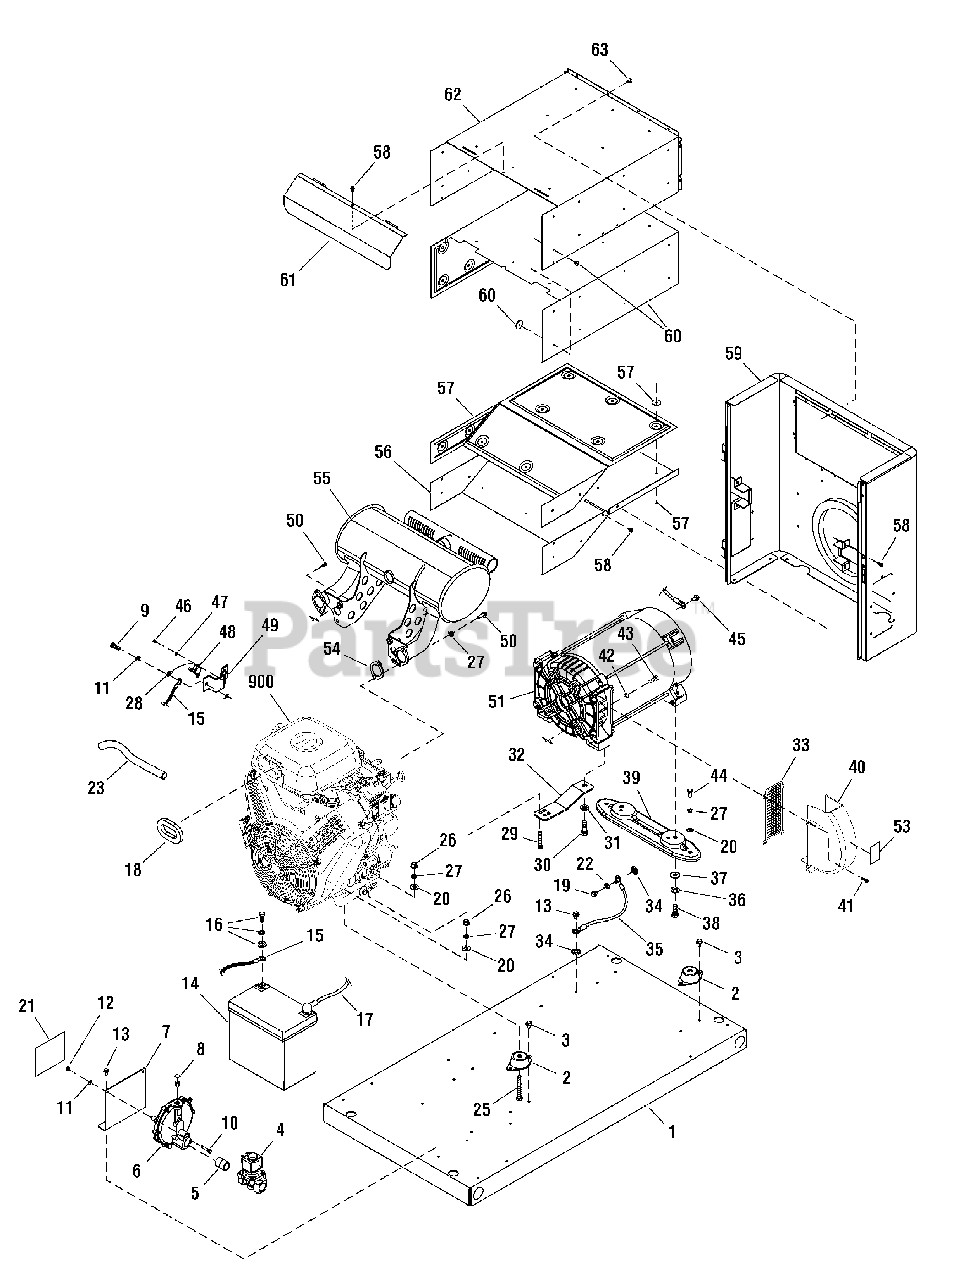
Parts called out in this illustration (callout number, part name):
1	BASE
2	MOUNT, Vibration
4	SOLENOID, Gas Fuel
6	REGULATOR, NG/LPG
7	BRACKET
9	* CAPSCREW, Hex Head, M6-1.0 x 16
10	* CAPSCREW, Hex Head, M6-1.0 x 30
11	* WASHER, Lock, 1/4
12	* NUT, M6-1.0
13	BOLT
16	KIT, Hardware, Battery
18	TUBE
20	* WASHER, Flat, 5/16-M8
22	* WASHER, Shakeproof, M6
23	HOSE, Oil Drain
25	* CAPSCREW, Hex Head, 5/16-18 x 2-1/2
26	* NUT, 5/16-18
27	* WASHER, Lock, 5/16-M8
29	* CAPSCREW, Hex Head, 5/16-18 x 2
30	* CAPSCREW, Hex Head, M12-1.75 x 35
31	* WASHER, M12
32	SUPPORT, Engine
34	* WASHER, Shakeproof, M6-1/4
36	* WASHER, Lock, 3/8
37	* WASHER, Flat, 3/8
38	* CAPSCREW, Hex Head, 3/8-16 x 1
39	SUPPORT, Alternator
41	* SCREW, Taptite, M5-0.8 x 10
42	* WASHER, Lock, 3/8
43	* CAPSCREW, 3/8-16 x 1-1/4
44	* CAPSCREW, Hex Head, 5/16-18 x 3/4
45	BOLT
46	* SCREW, Phillips Head, 4-40 x 0.19
47	* WASHER, Lock, #4
48	SWITCH, Temp
49	PLATE, Temp Switch
50	SCREW
51	ALTERNATOR
59	BULKHEAD, Alternator
62	BOX, Muffler, Top
900	** ENGINE
